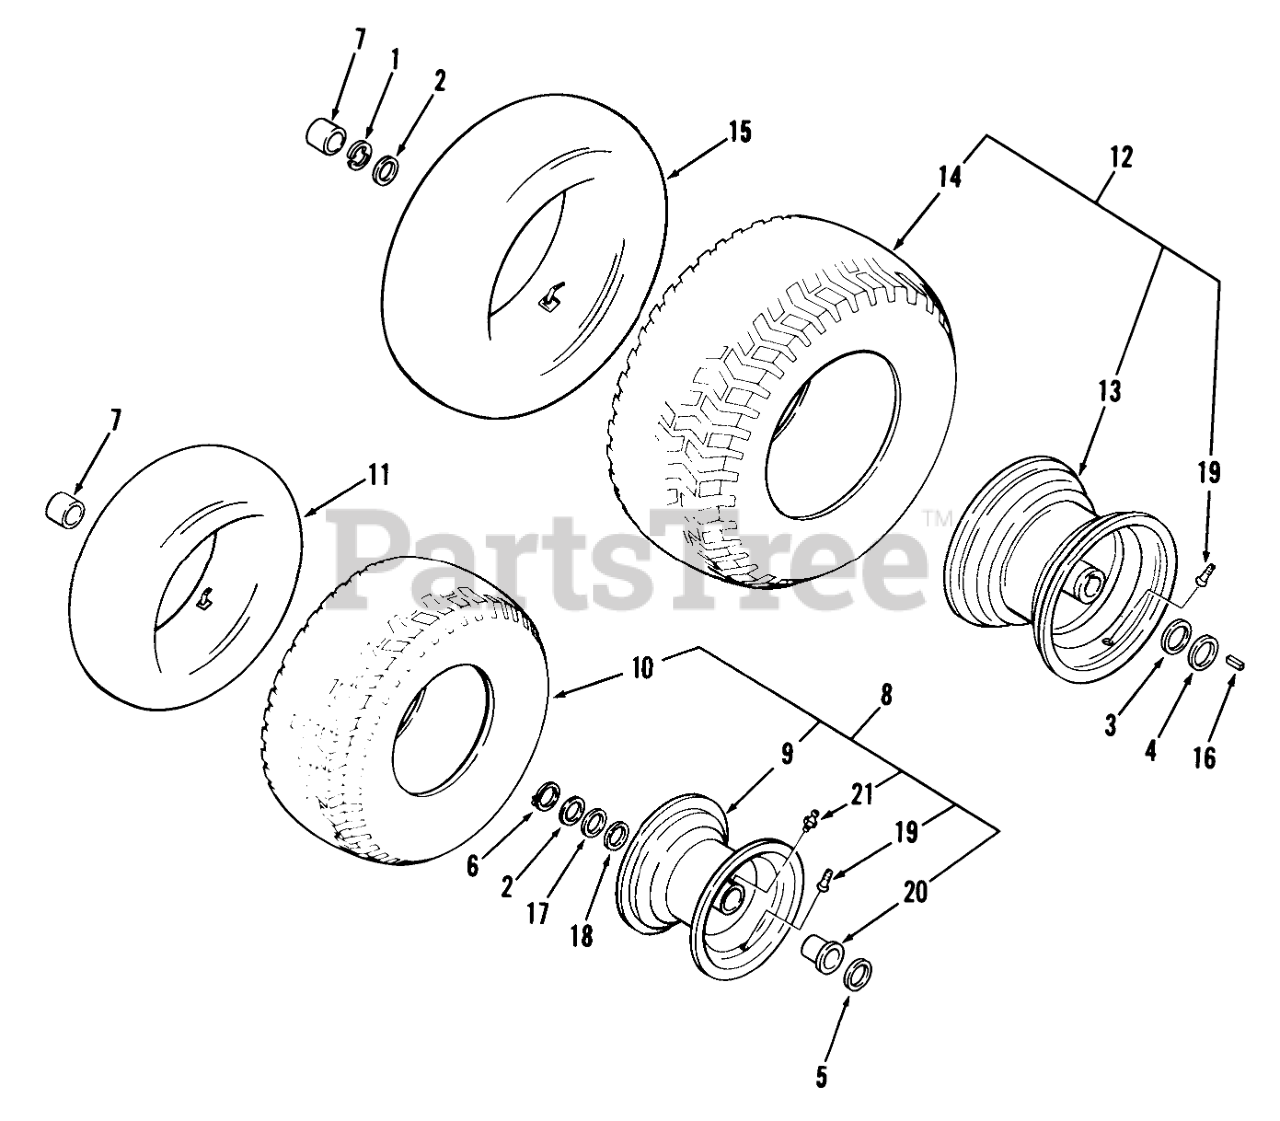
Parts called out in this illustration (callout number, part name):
1	E Ring
3	WASHER-SHIM
4	WASHER
5	Washer
6	Snap Ring
7	HUB CAP
8	Front Wheel
8	Assy-Wheel & Tire Front
9	Rim
9	Front Wheel
10	TIRE
11	Front Tube-Service Only
11	Tube (Service Only)
12	Assy-Wheel & Tire Rear
14	TIRE 18 X 8.50 X 8
14	TIRE 18 X 9.50-8
15	TUBE-TIRE
15	Tube-Inner
16	SQ KEY
17	WASHER
18	WASHER-SHIM
19	VALVE
20	Bearing
21	Zerk
